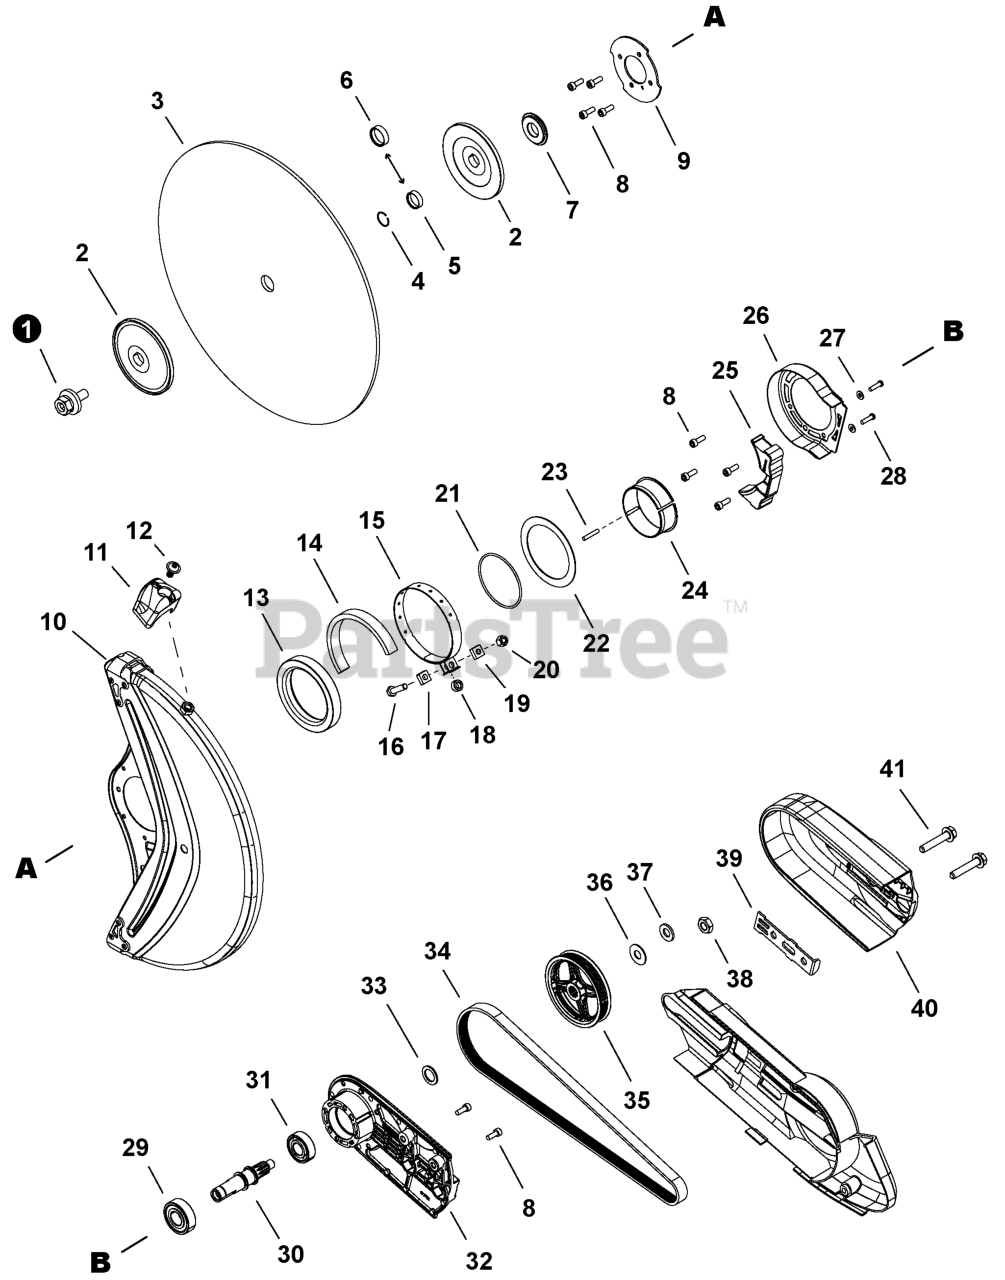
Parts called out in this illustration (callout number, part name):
1	BOLT ASSY
2	FLANGE ASSY, CUTTER
3	CUT-OFF WHEEL
4	RING, SNAP
5	ADAPTER, BLADE 20
6	ADAPTER, BLADE 25.4
7	COLLAR 18
10	COVER, CUTTER
13	CUSHION
14	CUSHION
16	BOLT 6x25
18	COLLAR 6
24	RING, SLIDE
25	HOLDER, CUSHION
26	COVER, SPRING
27	WASHER 4 MM
28	SCREW 4
29	BEARING, BALL 6203
30	DRIVESHAFT
31	BEARING, BALL 6202 DDU
32	CASE ASSY
34	BELT, DRIVE
36	WASHER 11
37	WASHER, CONICAL
38	NUT 3N-10
39	PLATE, EYE
40	COVER, CUTTER ARM
